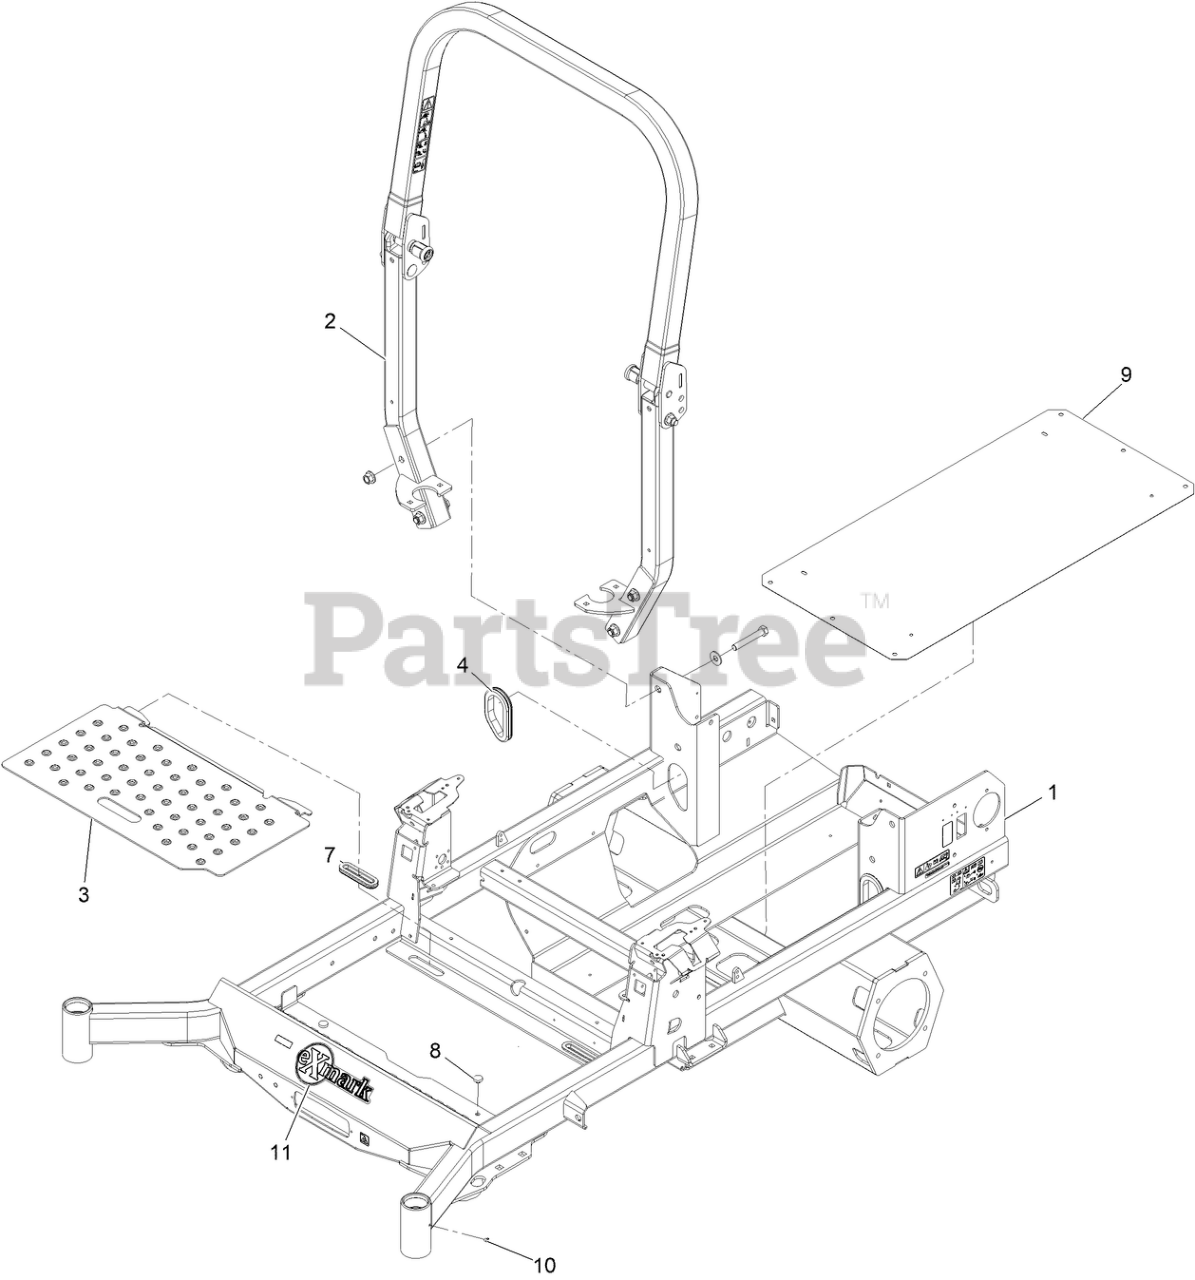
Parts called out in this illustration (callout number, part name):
1	Frame-Lzv60 W/ Decals
2	ASM-ROPS
4	GROMMET-RUBBER
7	GROMMET-RUBBER
9	PLATE-SKID
11	DECAL-EXMARK
